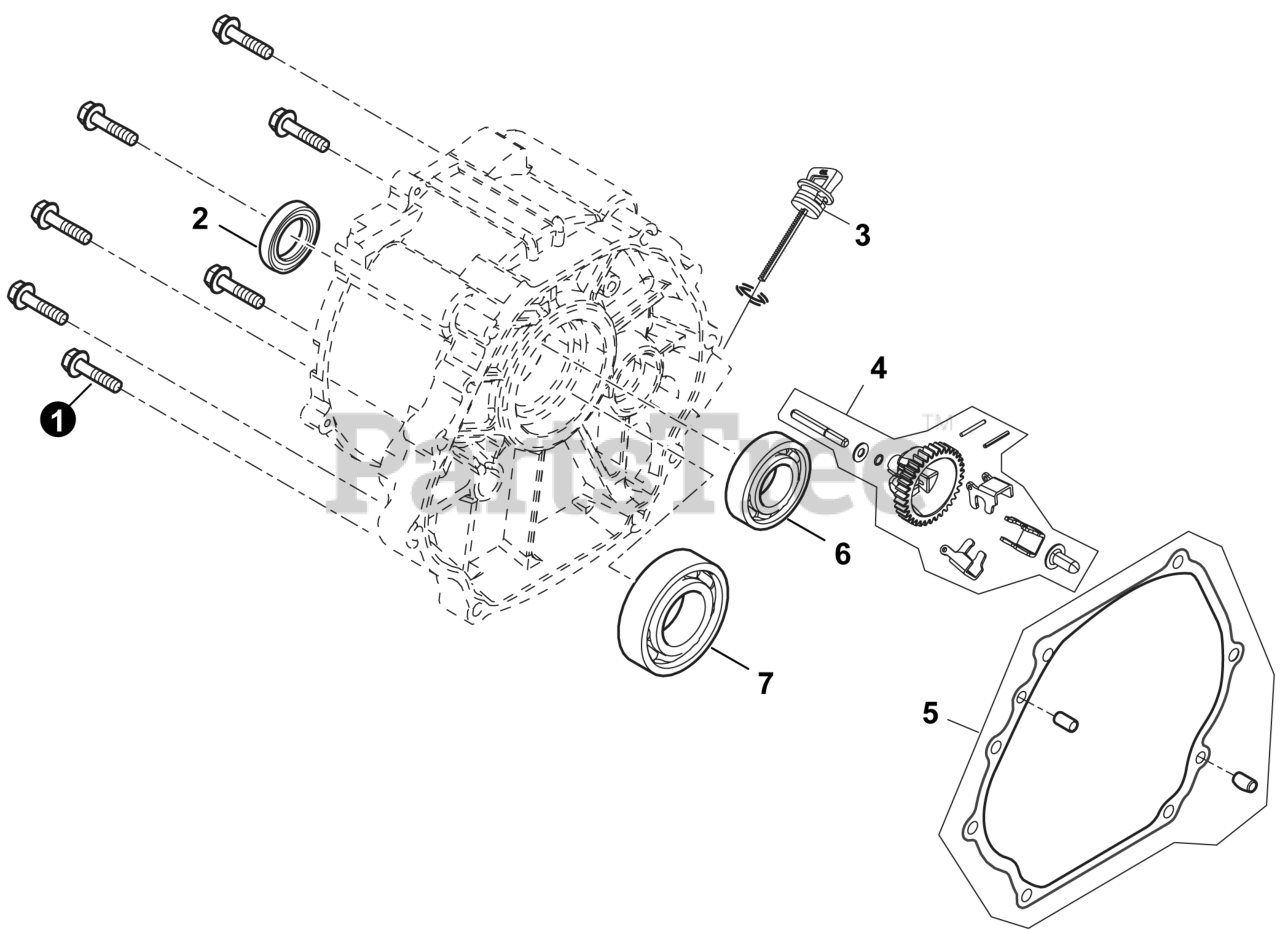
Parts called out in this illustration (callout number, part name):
2	SEAL, OIL
3	DIPSTICK, OIL
4	GEAR ASSY., GOVERNOR
5	GASKET, CRANKCASE
6	BEARING, CRANKSHAFT
7	BEARING, DEEP GROOVE BALL
